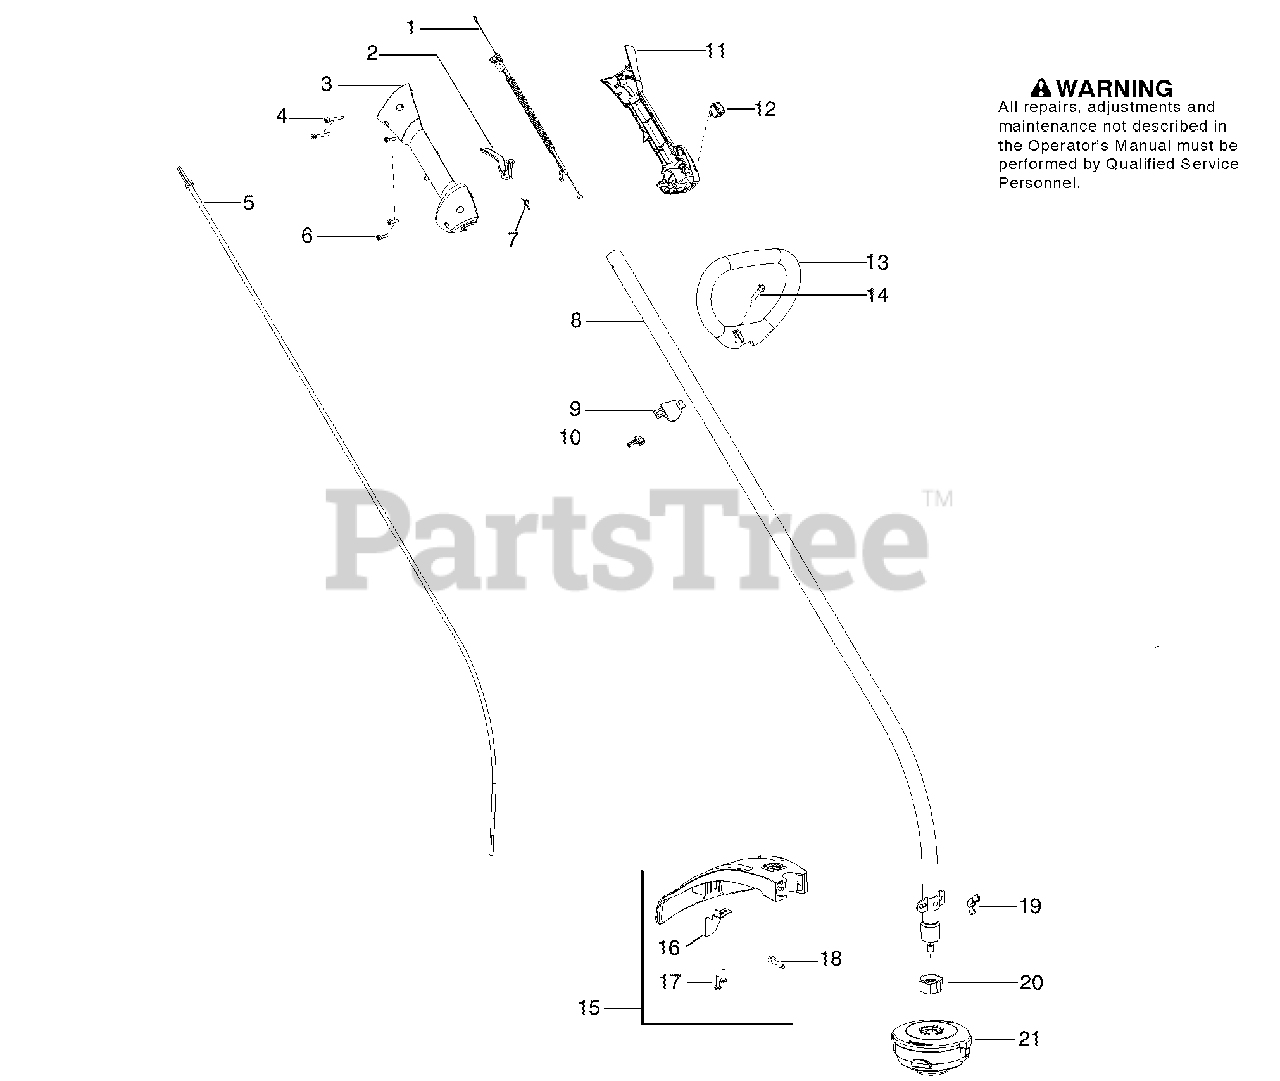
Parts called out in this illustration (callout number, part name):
1	Assy-Cable/Wire Harness
3	Housing-Throttle
5	Flexshaft
7	Spring-Trigger
8	Kit-Driveshaft
9	Clamp-Handle
10	Wingnut
11	Housing-Throttle
12	Kit-Switch
13	Handle-Assist
15	Kit-Shield
16	Kit - Limiter-Line
19	Wingnut
21	Assy-T25 Cutting Head
